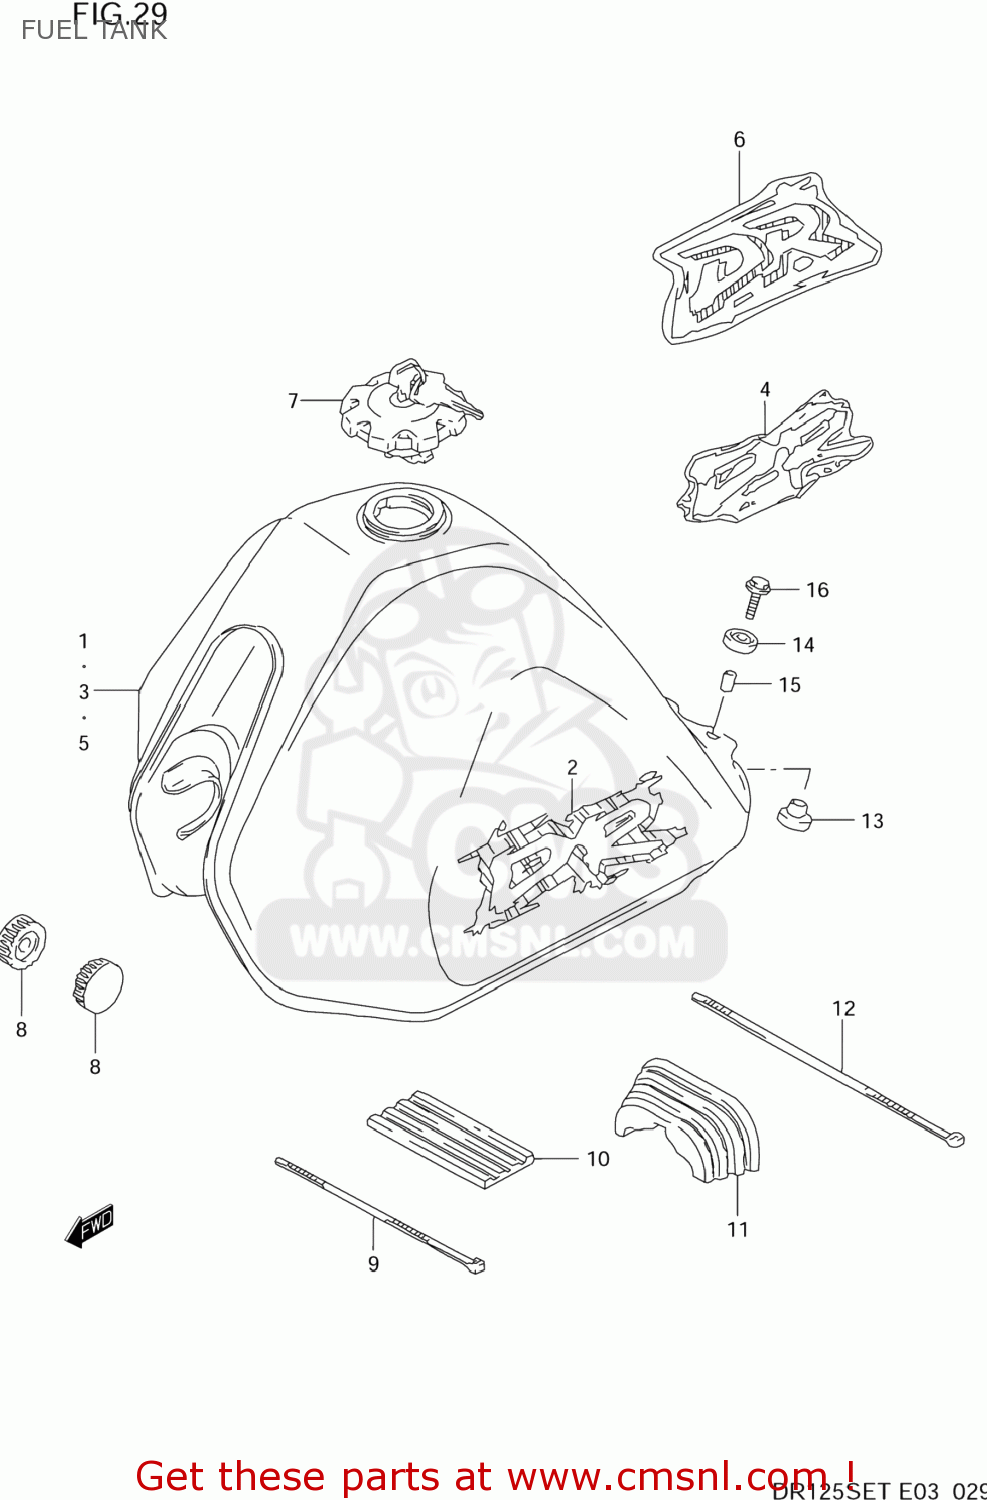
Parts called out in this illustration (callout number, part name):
1	TANK ASSEMBLY,FUEL
2	EMBLEM SET,FUEL TANK
3	TANK ASSEMBLY,FUEL
4	EMBLEM SET,FUEL TANK
5	TANK ASSEMBLY,FUEL
6	EMBLEM SET,FUEL TANK
7	CAP SET,FUEL TANK
8	CUSHION
9	CLAMP
10	CUSHION,FUEL TANK UPR FR
11	CUSHION,FUEL TANK RR
12	CLAMP(L:300)
13	CUSHION
14	CUSHION
15	SPACER
16	BOLT
